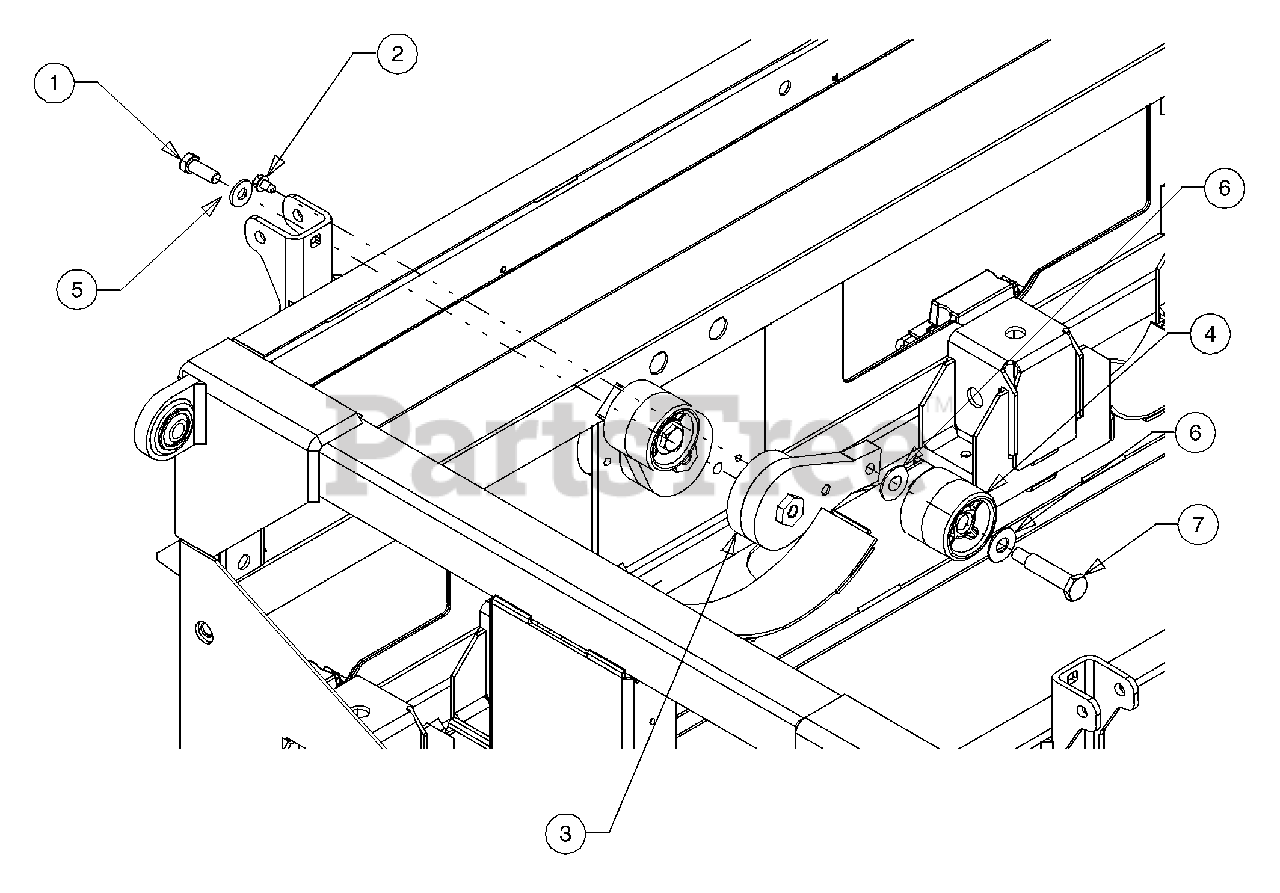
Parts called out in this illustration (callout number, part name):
1	Hex Screw, 3/8-16 x 1.0
2	Screw, Self-tapping, 1/4-20 x .5
3	Adjuster, Rotary
4	Roller, Chain
5	Washer, Flat, .385 x .870 x .092
6	Washer, Flat, .510 x 1.12 x .060
7	Shoulder Screw, .50 x 1.825
